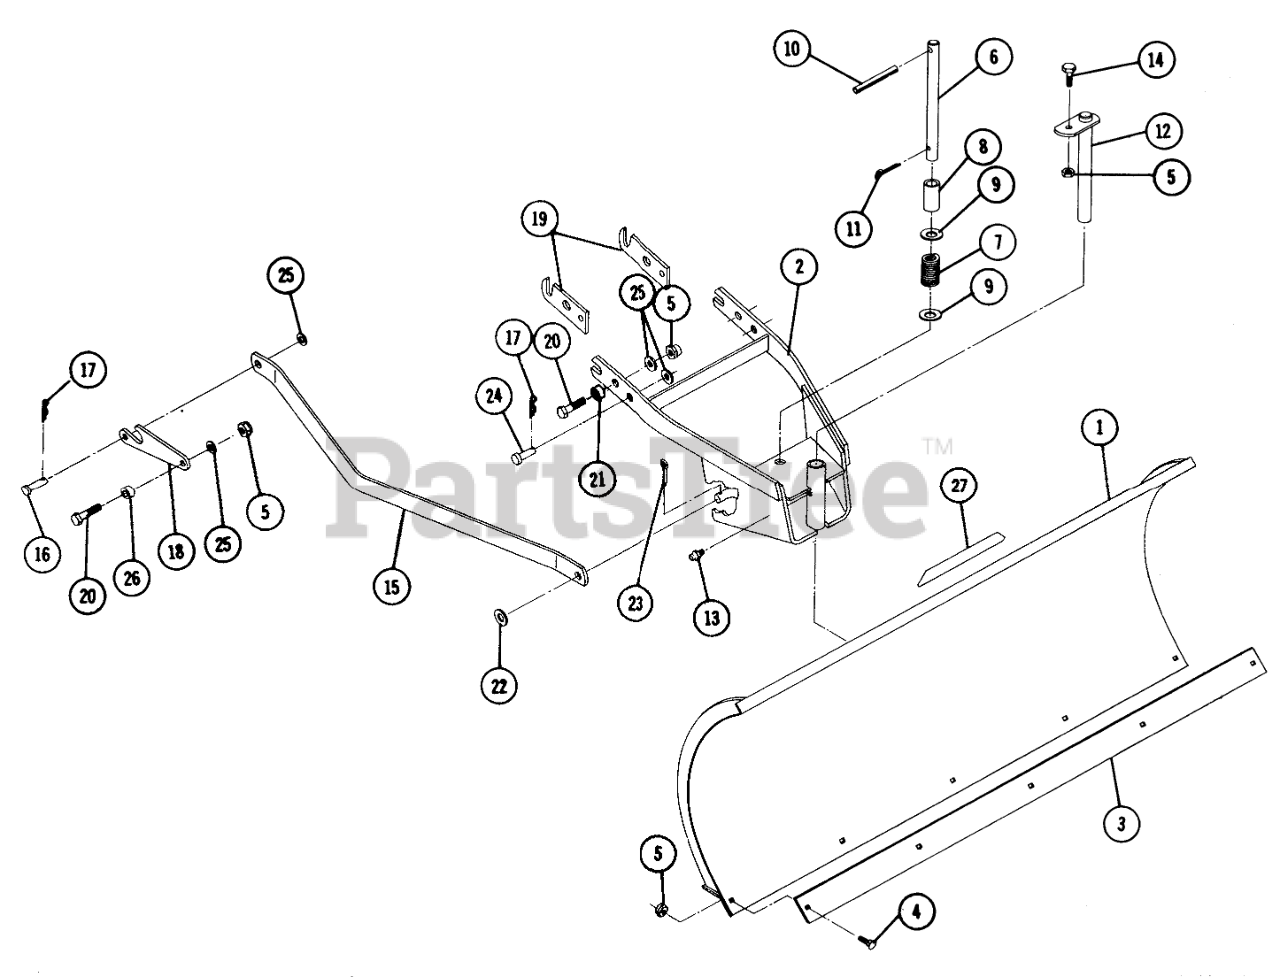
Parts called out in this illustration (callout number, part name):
1	Blade
2	Channel
3	Wear Plate
4	Bolt 3/8-16 x 1
5	3/8-16 E.S.
6	Pin-Pawl
7	Spring-Compression
8	SPACER
9	Washer, 5/8
10	Roll Pin 1/4 x 2 1/2
11	Cotter Pin
12	Pivot Pin
13	Zerk
14	Bolt 3/8-16 x 3/4
15	Bar-lift
17	Hairpin
18	Connector
19	Latch
20	Bolt 3/8-16 x 1
21	SPACER
22	Washer
23	Cotter Pin 3/16 x 1
24	Clevis Pin
25	Washer
26	SPACER CLUTCH ARM
27	Decal
